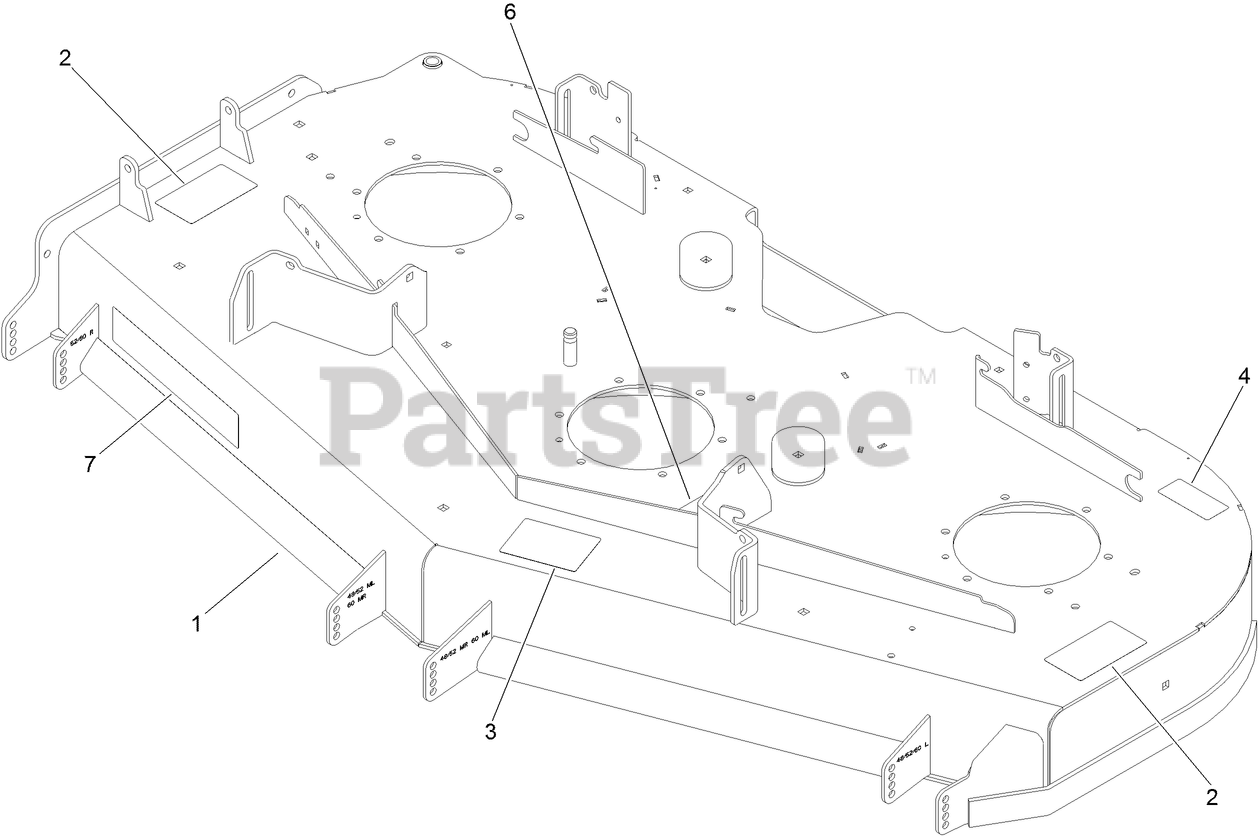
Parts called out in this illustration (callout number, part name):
2	DECAL-DANGER
3	DECAL-SCALP, ANTI
4	DECAL-BOLT TORQUE
6	DECAL-ROUTING, BELT
